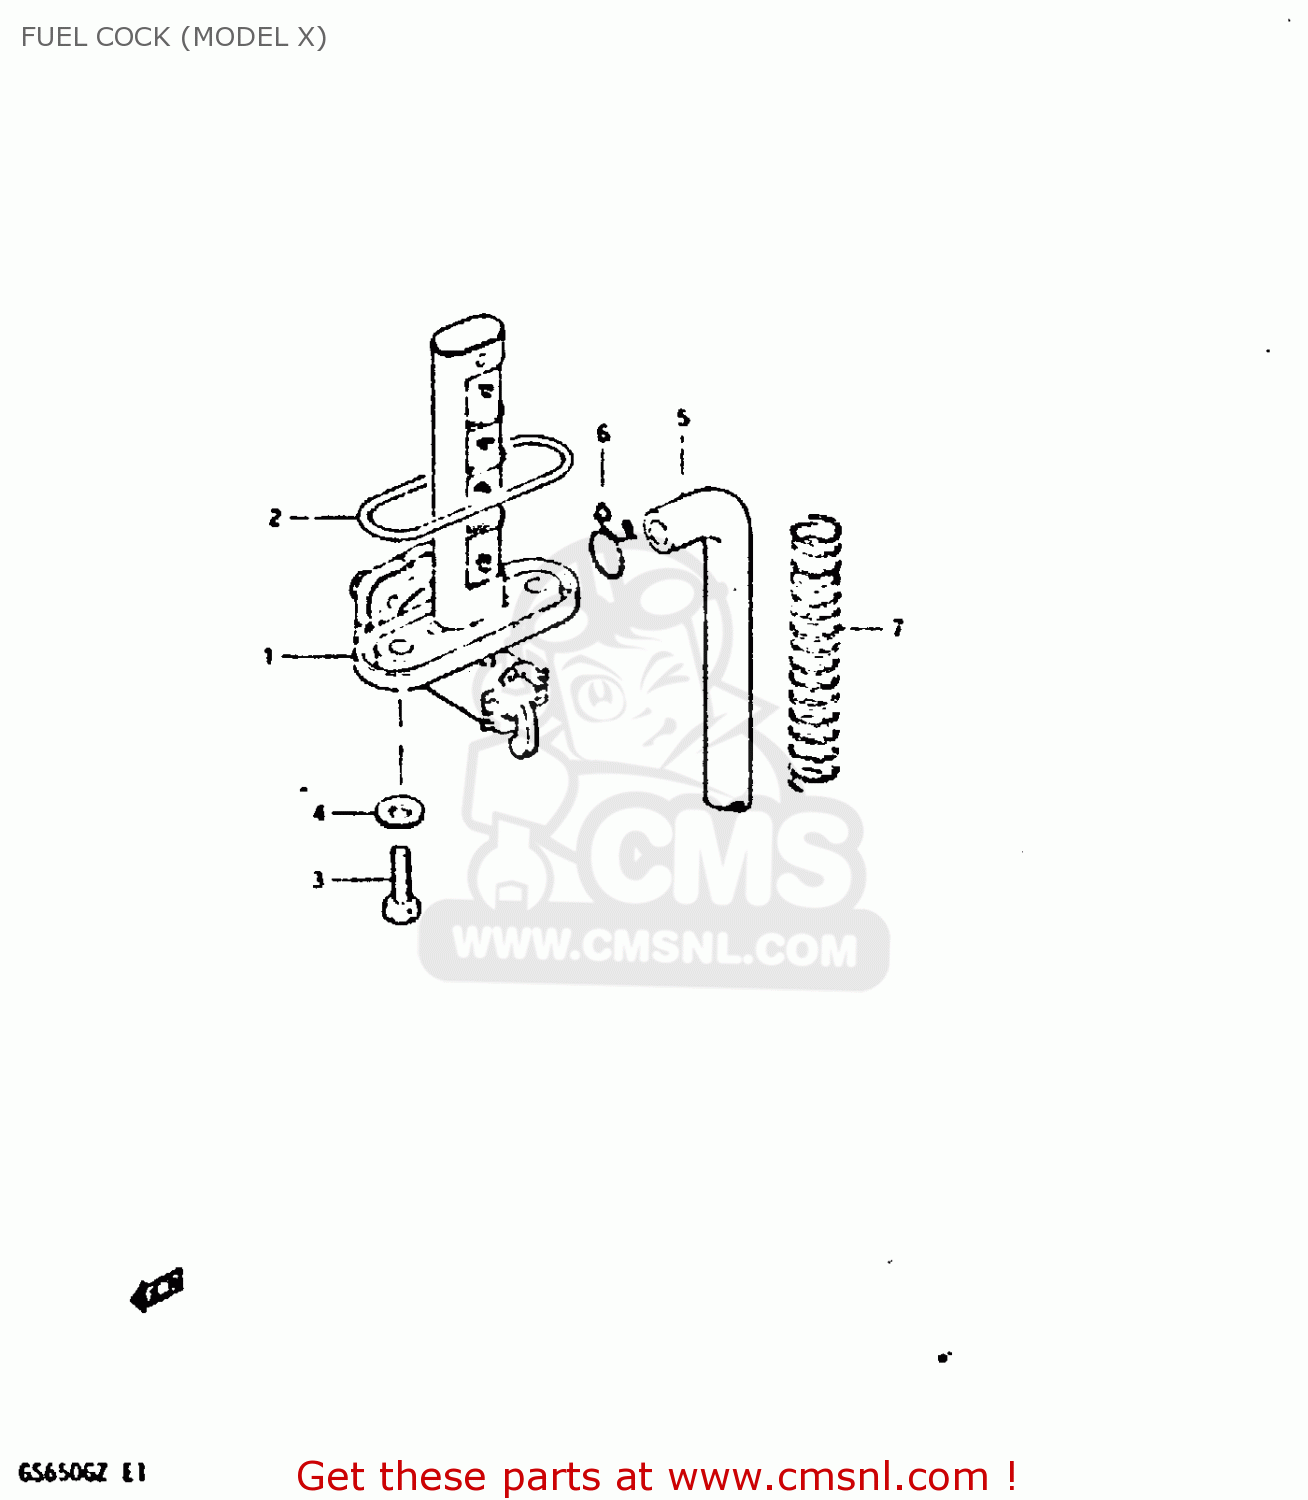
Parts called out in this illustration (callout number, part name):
1	COCK ASSEMBLY,FUEL
2	O RING
3	BOLT(6X20)
4	GASKET
5	HOSE
6	CLIP
7	SPRING
